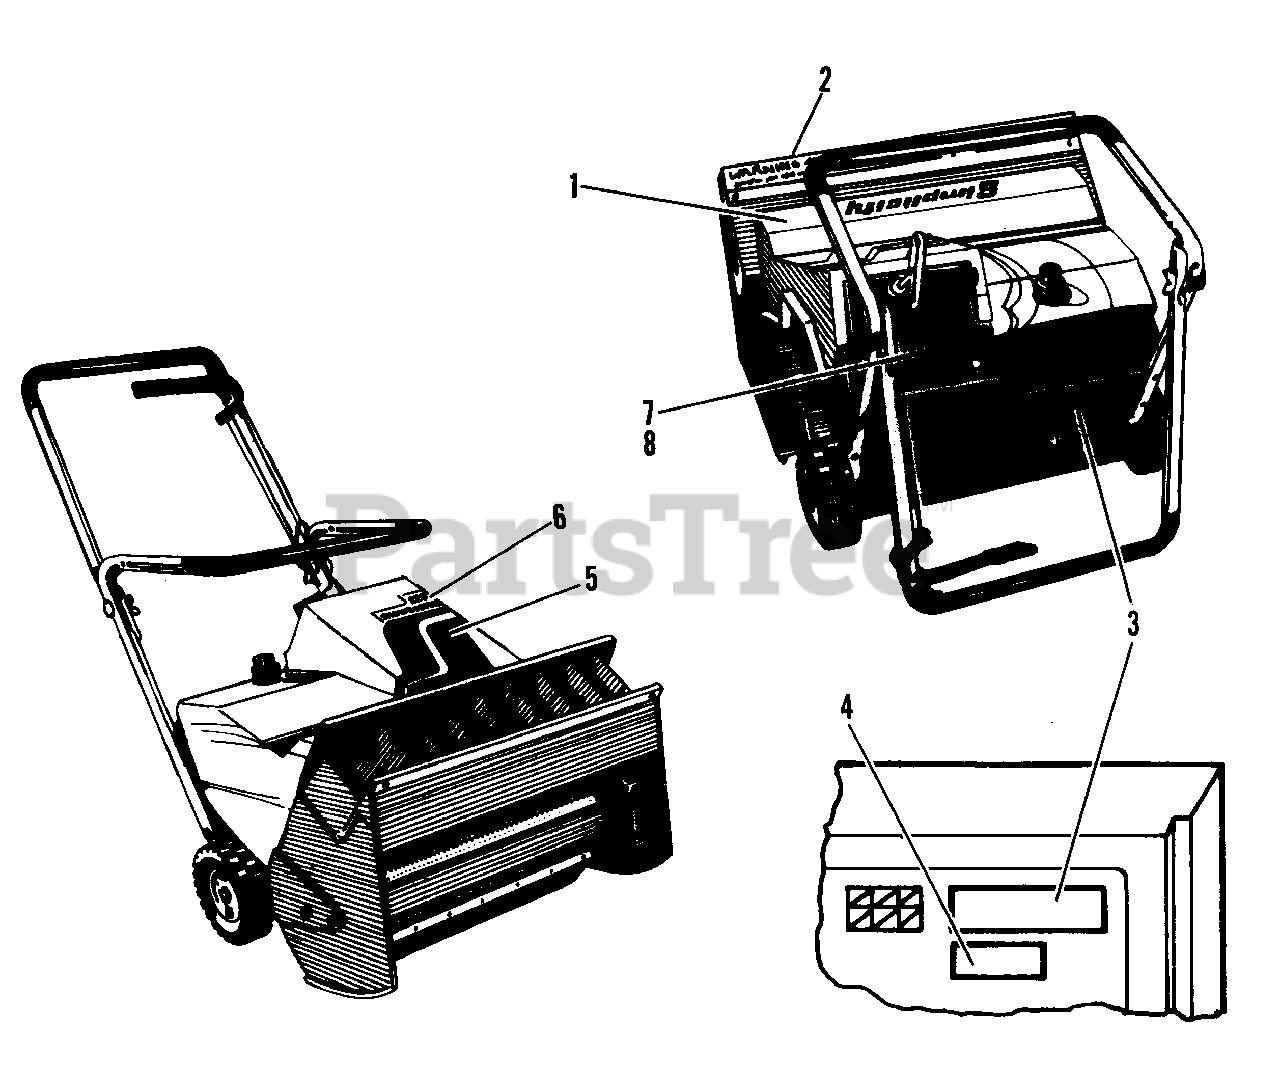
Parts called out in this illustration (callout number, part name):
1	DECAL, Simplicity
2	DECAL, Warning
3	DECAL, I.D.
4	DECAL, Patent
5	DECAL, Stripe
6	DECAL, Snowbuster
7	DECAL, Dash (Electric Start)
8	DECAL, Dash (Manual Start)
